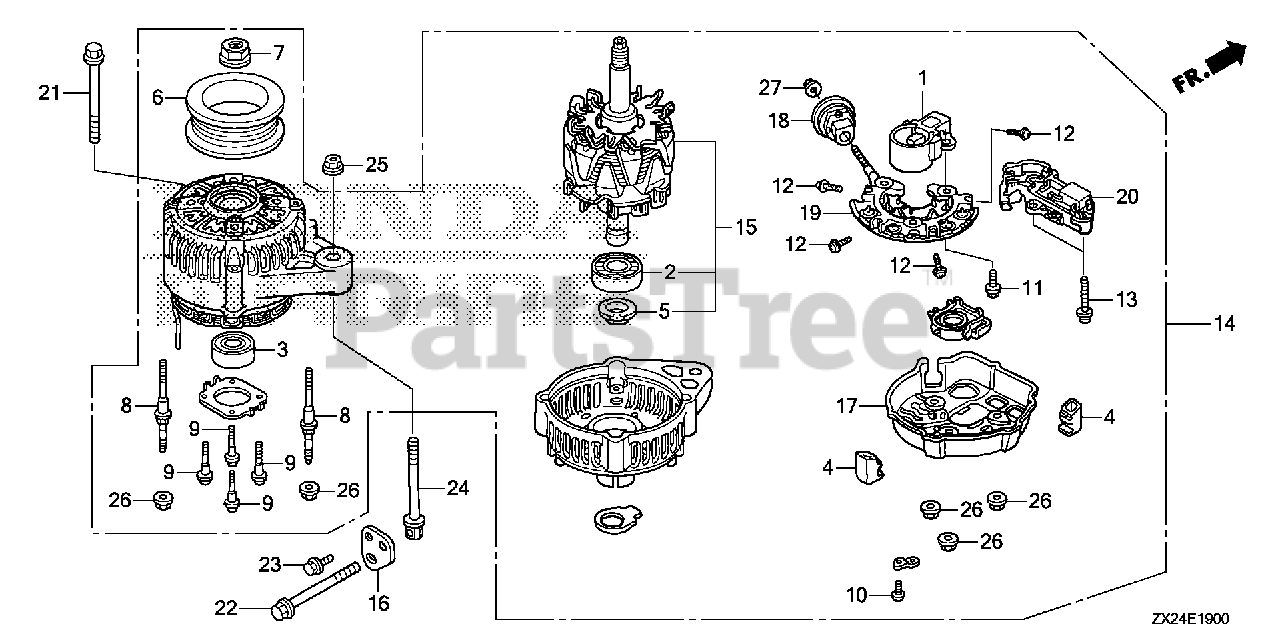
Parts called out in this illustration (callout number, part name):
1	HOLDER ASSY., BRUSH
2	BEARING, RR. GENERATOR
3	BEARING, FR. GENERATOR
4	BUSH, INSULATION
5	COVER, BEARING
7	NUT, PULLEY LOCK
8	BOLT, STUD (6X68)
11	SCREW-WASHER
12	SCREW, WAVE WASHER
13	SCREW, WAVE WASHER
14	ALTERNATOR ASSY.
15	ROTOR ASSY.
16	STAY, ALTERNATOR
17	END COVER, RR.
18	BUSH, INSULATION
19	RECTIFIER ASSY.
20	REGULATOR ASSY.
21	BOLT, FLANGE (10X90)
22	BOLT, SPECIAL ADJUSTER
23	BOLT, FLANGE (6X16)
24	BOLT, TENSIONER
25	NUT, FLANGE (8MM)
26	NUT-WASHER (5MM)
27	NUT, HEX. (6MM)
